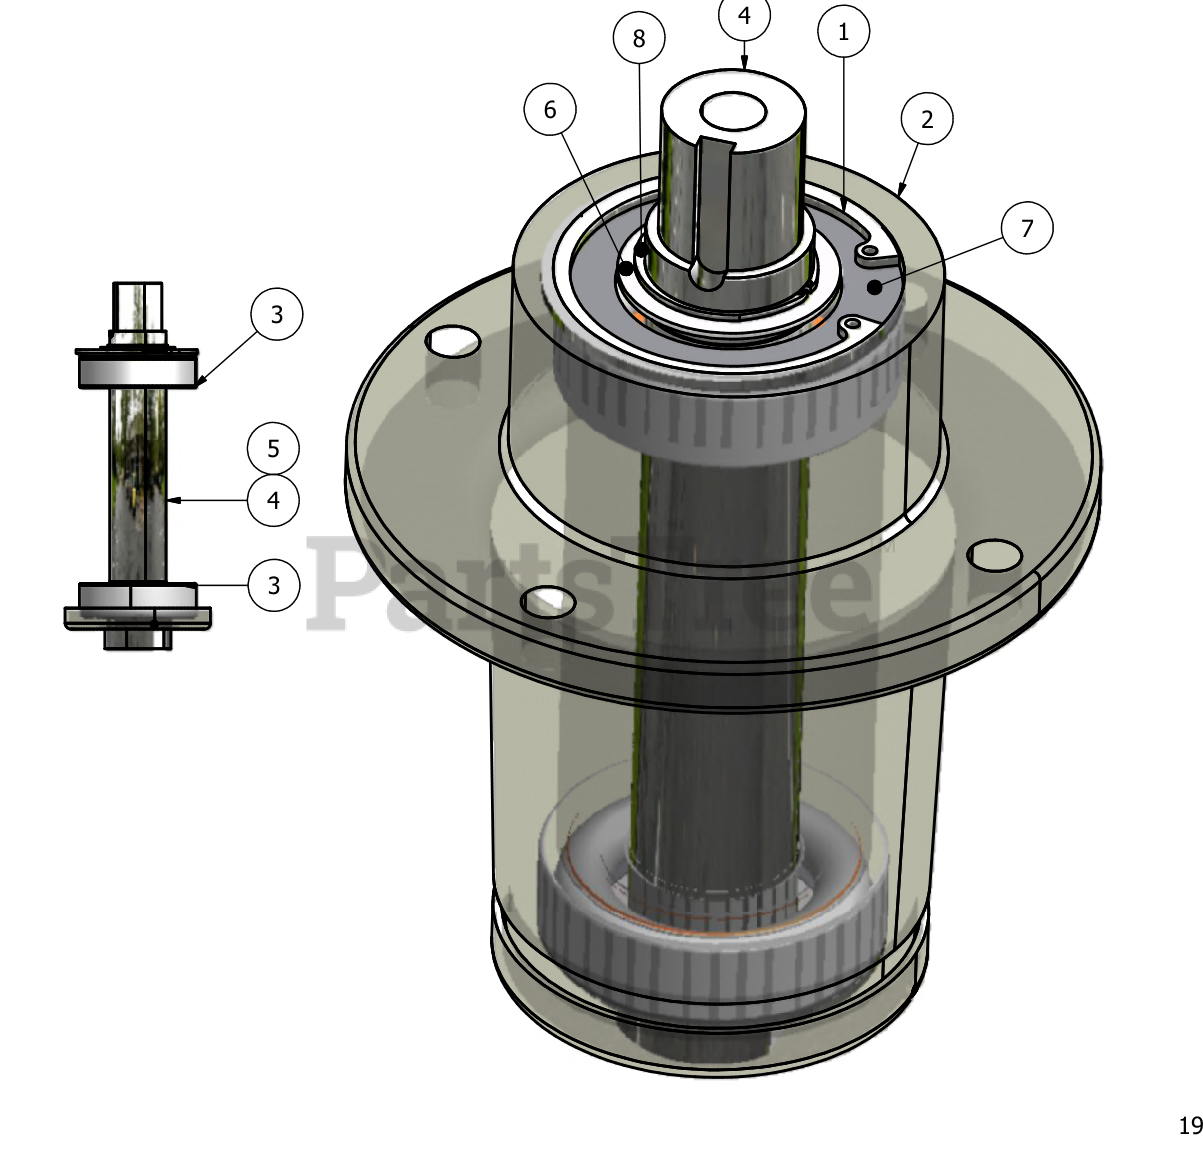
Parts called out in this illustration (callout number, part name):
1	Bearing Retainer Ring
2	Spindle Housing
4	Short Shaft
5	Long Shaft
6	Small Bearing Spacer
7	Large Bearing Spacer
8	Shaft Retainer Ring
